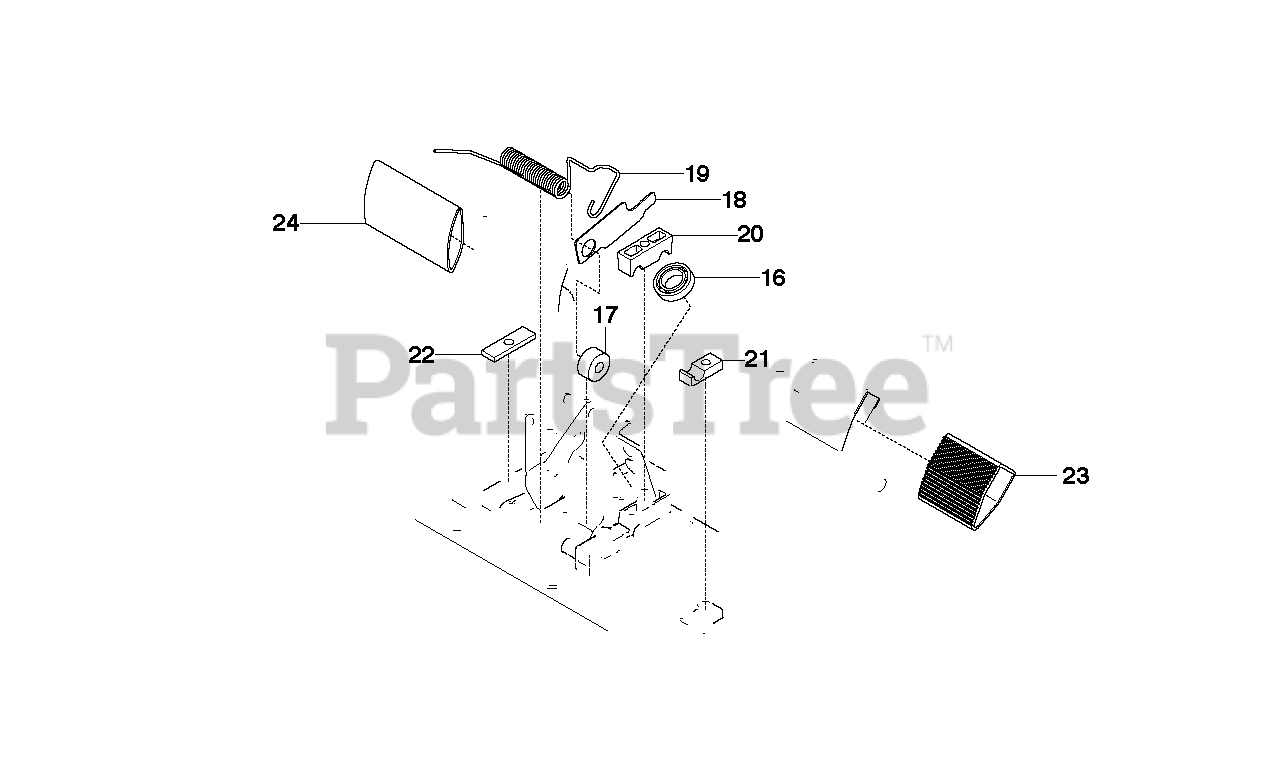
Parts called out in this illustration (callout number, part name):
16	BALL BEARING 6002-2RS1
17	ROLLER
18	PLATE
19	SPRING
20	PEDAL SHAFT CLAMP
21	SUPPORT
22	PLATE
23	PEDAL RUBBER
24	PEDAL RUBBER, SF
